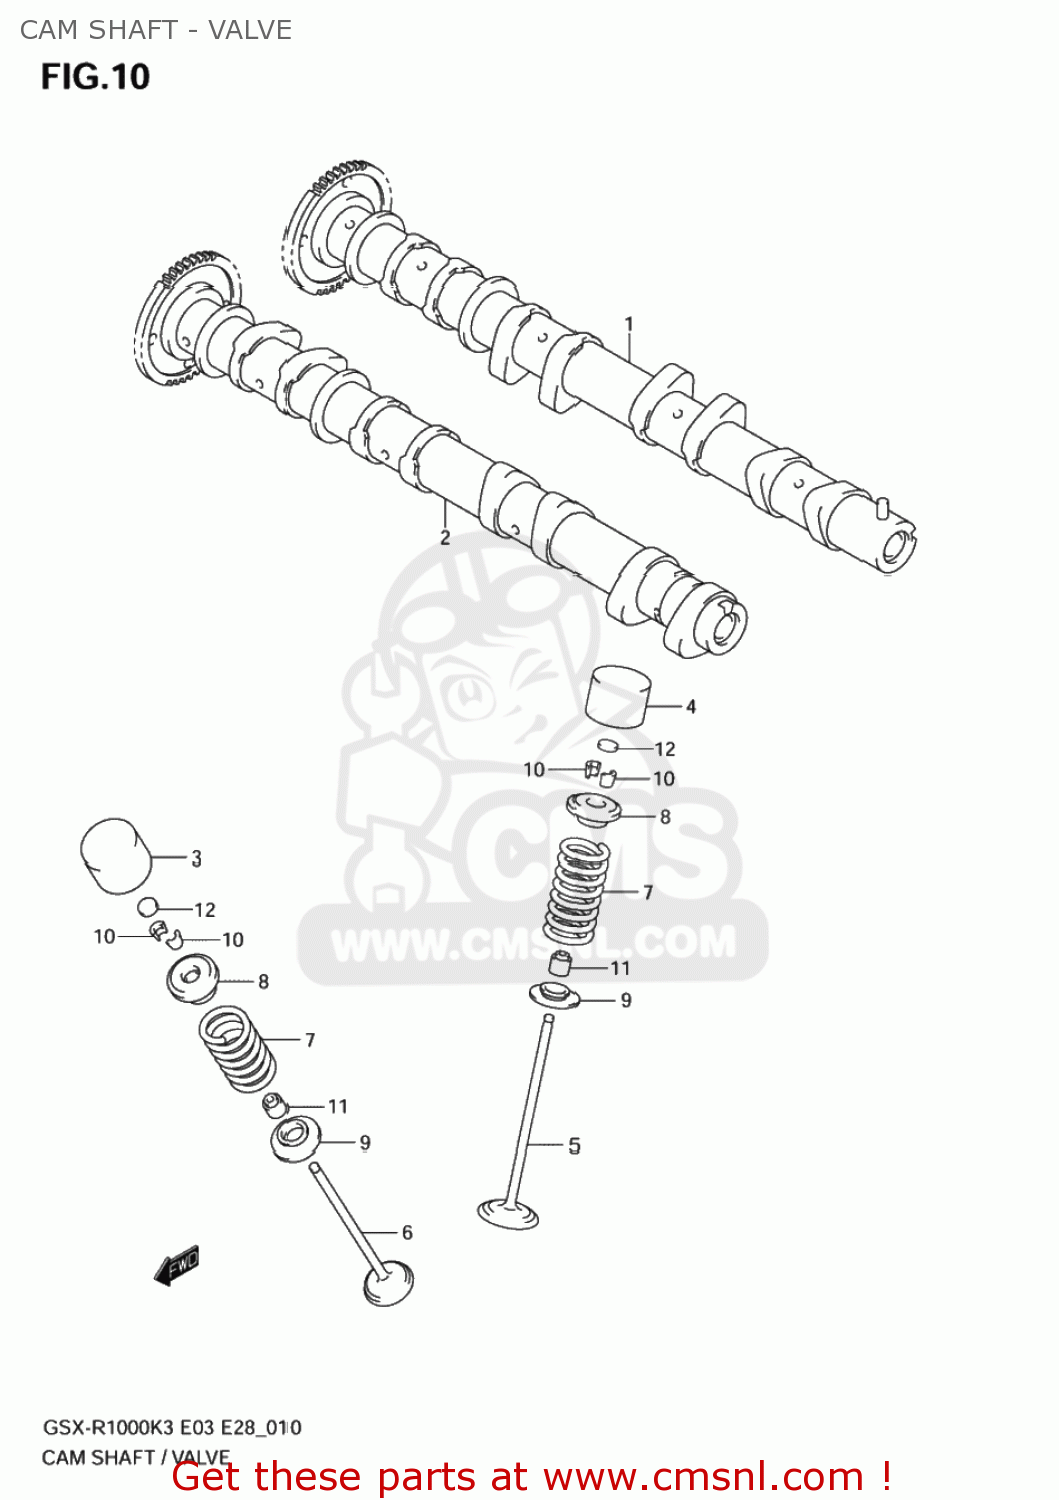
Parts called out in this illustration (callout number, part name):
1	CAMSHAFT,INTAKE
2	CAMSHAFT,EXHAUST
3	TAPPET,EXHAUST
4	TAPPET
5	VALVE,INTAKE
6	VALVE,EXHAUST
7	SPRING,VALVE
8	RETAINER,VALVE SPRING
9	SEAT,VALVE SPRING
10	COTTER VALVE
11	SEAL,OIL(3.2X8.6X9)
12	SHIM,TAPPET
13	SHIM SET,TAPPET
14	CASE,TAPPET SHIM
